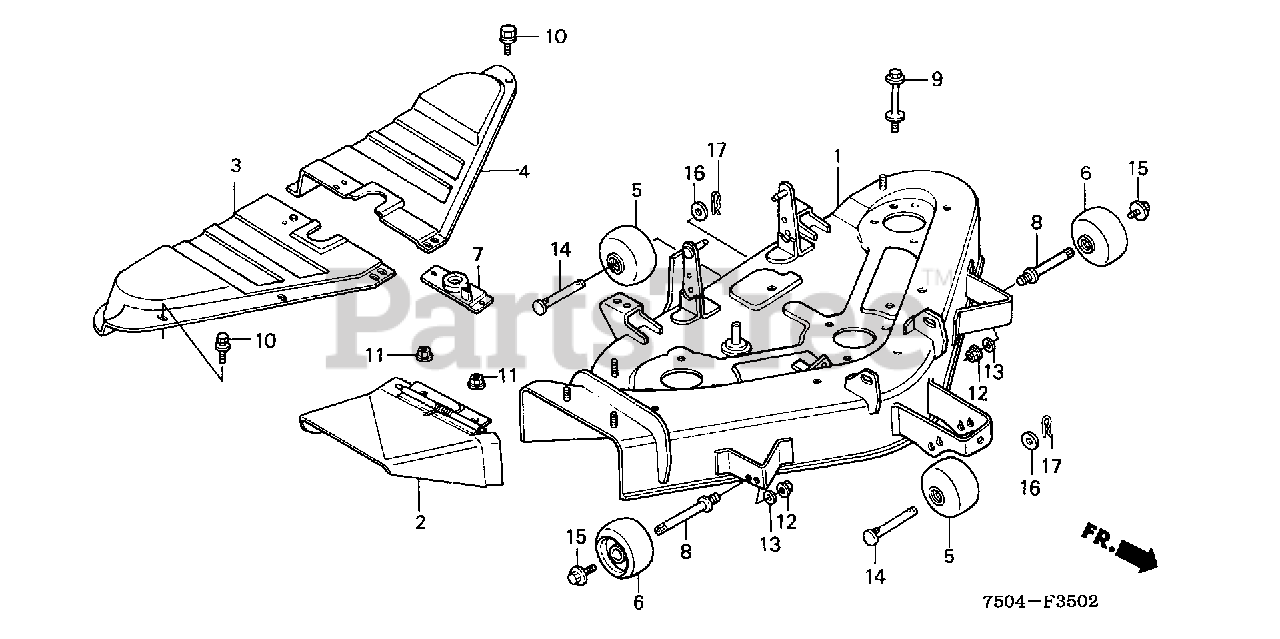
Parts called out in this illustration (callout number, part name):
1	HOUSING, CUTTER *NH190M* (VINTAGE GRAY METALLIC)
2	ADAPTER, DISCHARGE *NH190M* (VINTAGE GRAY METALLIC)
3	COVER, R. BELT *NH190M* (VINTAGE GRAY METALLIC) (NOT AVAILABLE)
4	COVER, L. BELT *NH190M* (VINTAGE GRAY METALLIC)
5	ROLLER, ANTI-SCALP
6	ROLLER, ANTI-SCALP
7	SEAL, BELT COVER *NH190M* (VINTAGE GRAY METALLIC) (NOT AVAILABLE)
8	SHAFT, ANTI-SCALP ROLLER
9	BOLT, BELT STOPPER
10	BOLT-WASHER (6X16)
11	NUT, SELF-LOCK (8MM)
12	NUT, SELF-LOCK (12MM)
13	WASHER, THRUST (12MM)
14	PIN, ANTI-SCALP ROLLER
15	BOLT-WASHER (8X12)
16	WASHER, FLAT (12MM)
17	PIN, LOCK (12MM)
